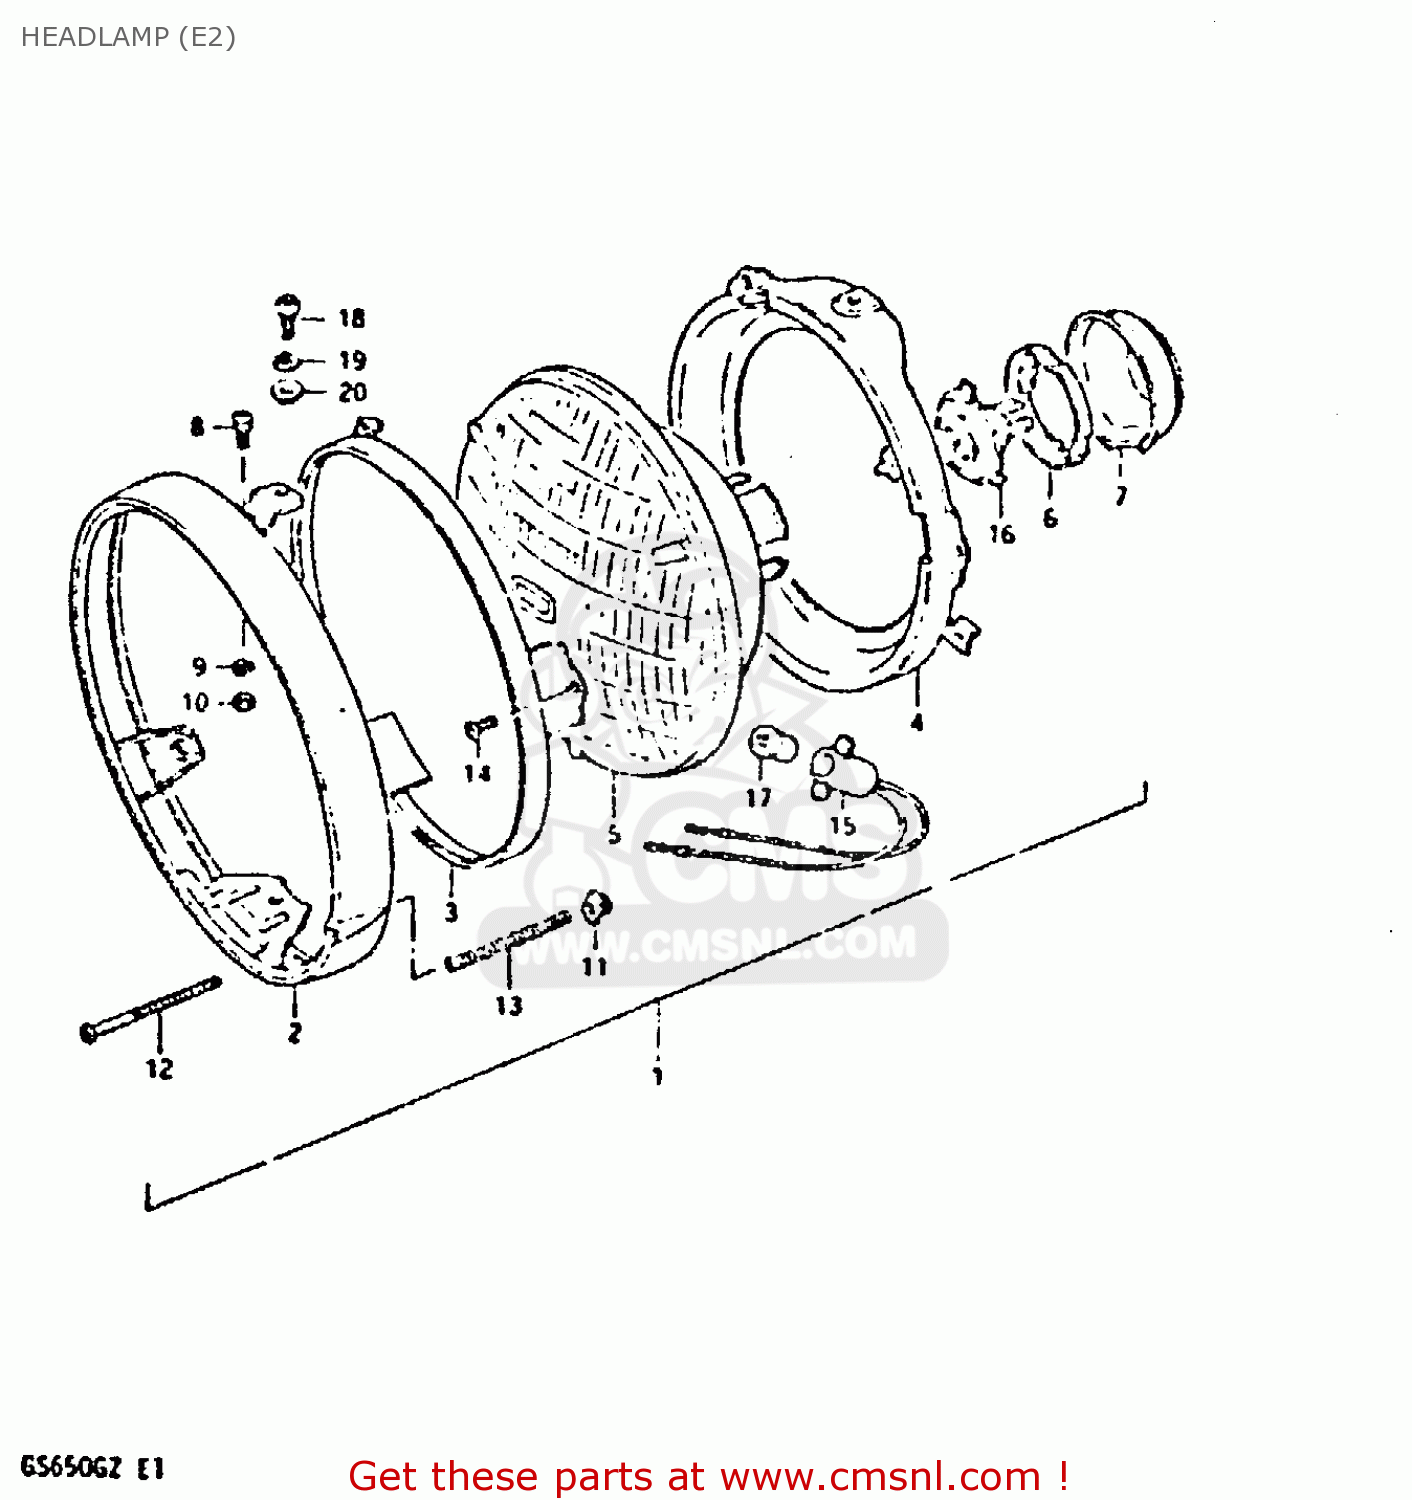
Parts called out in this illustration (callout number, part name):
1	HEADLAMP ASSY
2	RIM,HEADLAMP
3	RETAINING RING
4	RING
5	LAMP UNIT
6	SETTING,BULB
7	COVER,HEADLAMP SOCKET
8	H/LAMP LENS UNIT FITING SCRE
9	LOCK WASHER
10	NUT
11	NUT
12	SCREW,HEADLAMP ADJUST
13	SPRING,ADJUSTING
14	SCREW
15	SOCKET
16	BULB(12V60/55W,H4)
17	BULB(12V3.4W,STANLEY,A72A)
18	SCREW
19	WASHER,LOCK
20	WASHER
